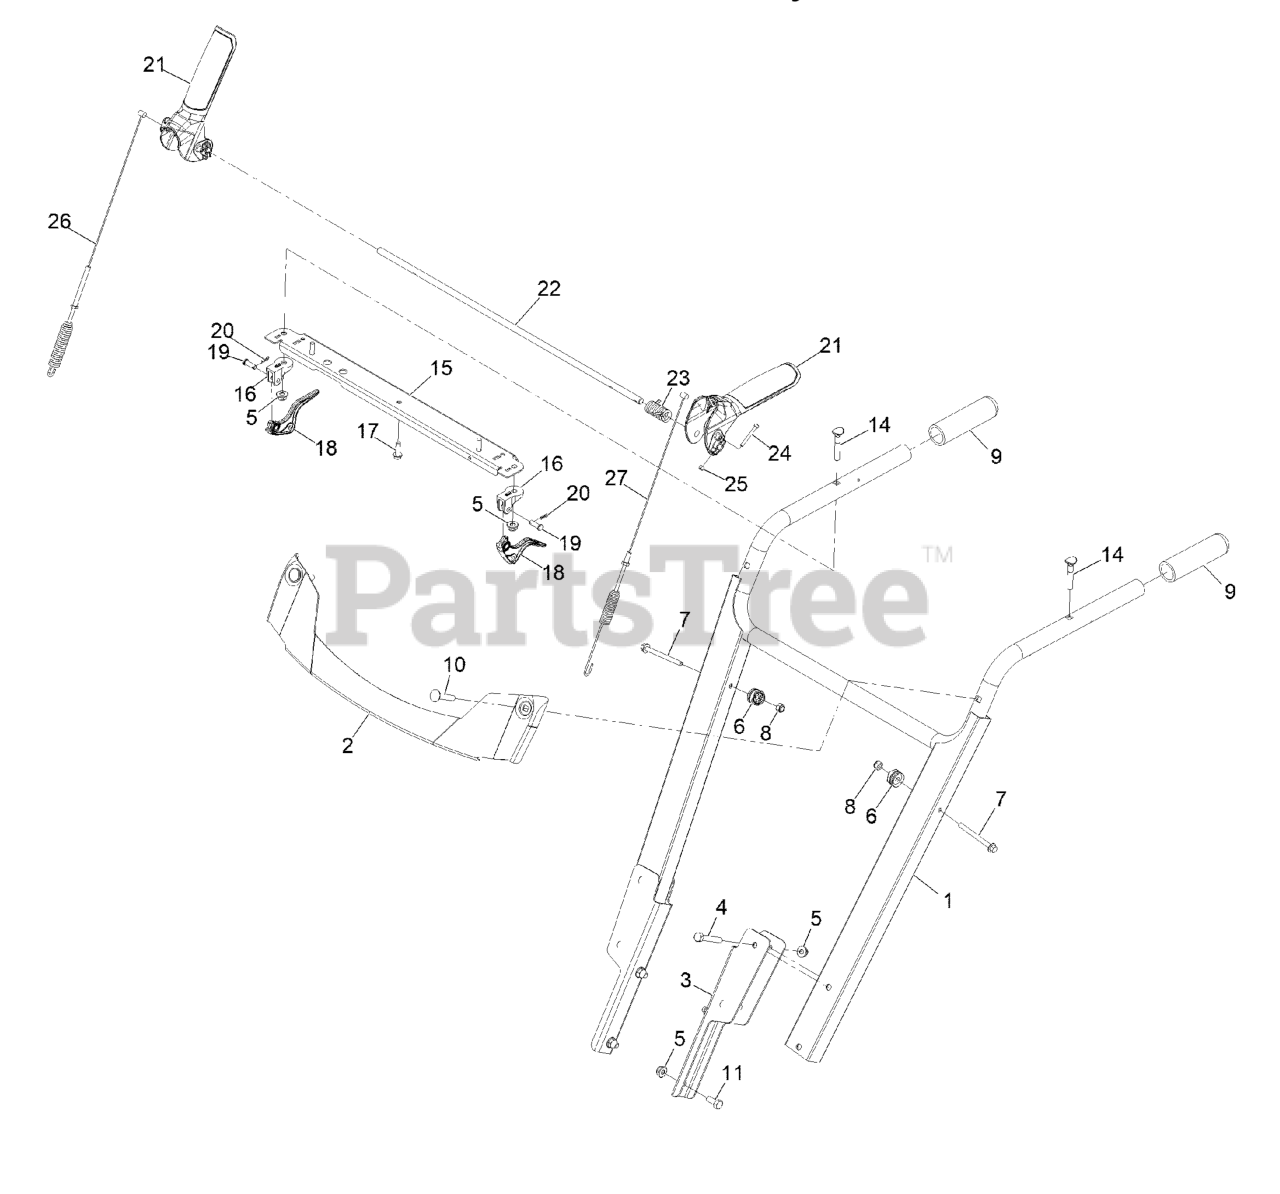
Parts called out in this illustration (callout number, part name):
1	HANDLE ASM HD, WELDED
2	METAL TRIM, HD
3	BRACKET-HANDLE, LOWER
4	SCREW-HH
6	CLAMP-CABLE
7	SCREW-HHF
8	NUT-HEX
9	GRIP-HANDLE
10	BOLT-CARR
11	SCREW-HH
14	SCREW-HANDLE
15	BRACE-CONSOLE
16	MOUNT-LEVER, CLUTCH
17	SCREW-PLASTITE, HWH
18	LEVER-CLUTCH
19	PIN-CLEVIS
20	PIN-HAIR
21	LEVER-CONTROL
22	Rod-Lockout
23	SPRING-TORSION, HANDLE RETURN
24	SCREW-HSH M4-0.7 X 36MM
25	NUT-HEX NYL INS M4-0.7
26	CABLE-AUGER
27	CABLE-TRACTION
